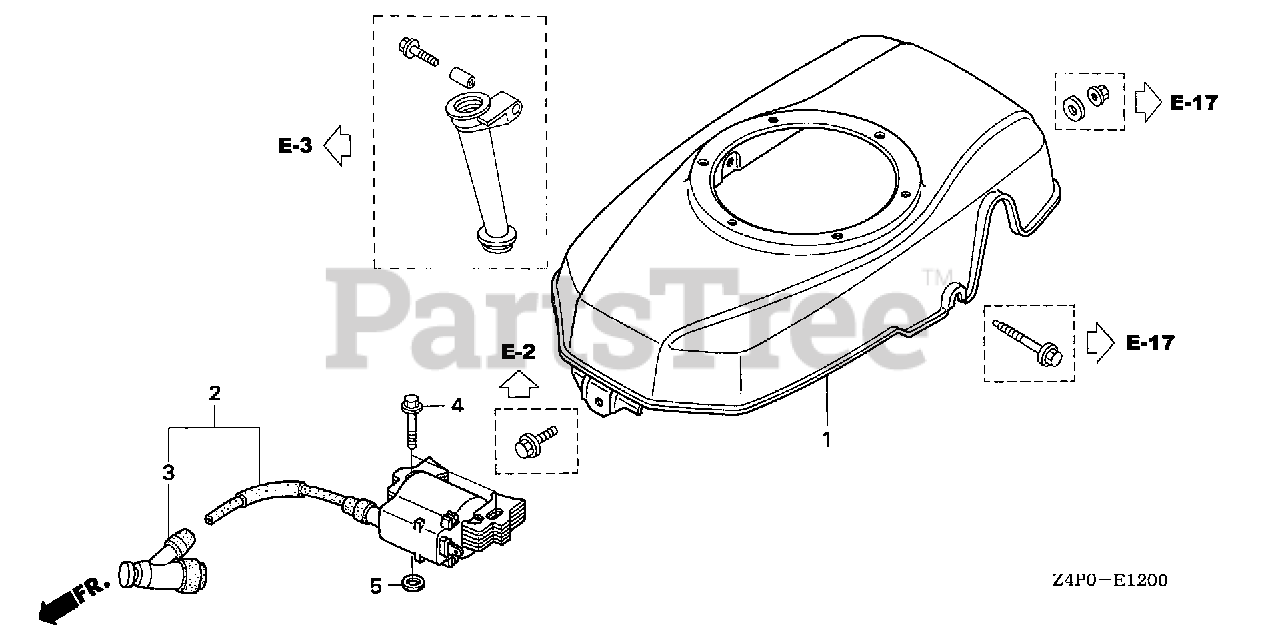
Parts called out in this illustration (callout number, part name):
1	COVER, FAN *R280* (POWER RED)
2	COIL ASSY., IGNITION
3	CAP ASSY., NOISE SUPPRESSOR
4	BOLT, FLANGE (6X28) (CT200)
5	WASHER, PLAIN (6MM)
